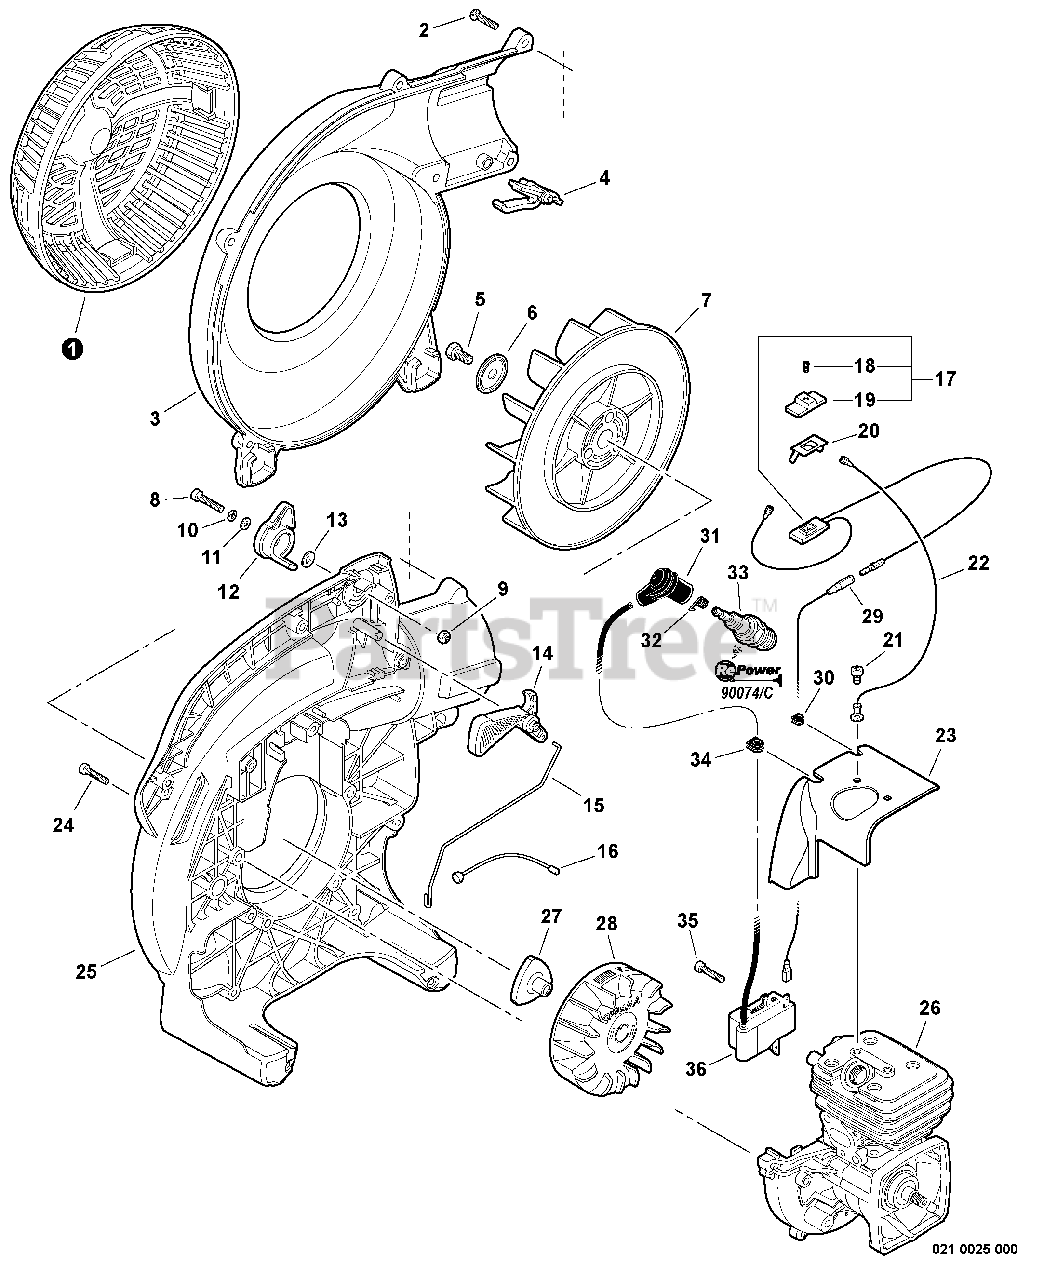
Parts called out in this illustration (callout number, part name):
1	GUARD, FAN
2	BOLT, TORX 5×20
3	COVER, FAN
4	LOCK, TUBE
5	BOLT 8×14
6	WASHER 8.2×31×0.8
7	FAN, BLOWER
8	BOLT, TORX 5×25
9	NUT, LOCK M5
10	WASHER, SPRING 5
11	WASHER 5.3×10×1
12	CONTROL, THROTTLE
13	WASHER 5.5×12×0.8
14	TRIGGER, THROTTLE
15	ROD, THROTTLE
16	CABLE, THROTTLE
17	SWITCH ASSY, ON-OFF
18	SCREW 3×10
19	KNOB, SWITCH
20	TERMINAL, LEAD
21	BOLT, TORX 5×8
22	LEAD L= 210 MM
23	SHIELD, CYLINDER
24	BOLT, TORX 4×20
25	CASE, FAN
26	SHORT BLOCK
27	HUB, FAN
28	FLYWHEEL
29	LEAD L= 85 MM
31	CAP, SPARK PLUG
32	TERMINAL, SPARK PLUG
33	SPARK PLUG - BPM8Y
33	SPARK PLUG - BPMR8Y
35	BOLT, TORX 4×20
36	COIL, IGNITION
37	TUNE-UP KIT - REPOWER
